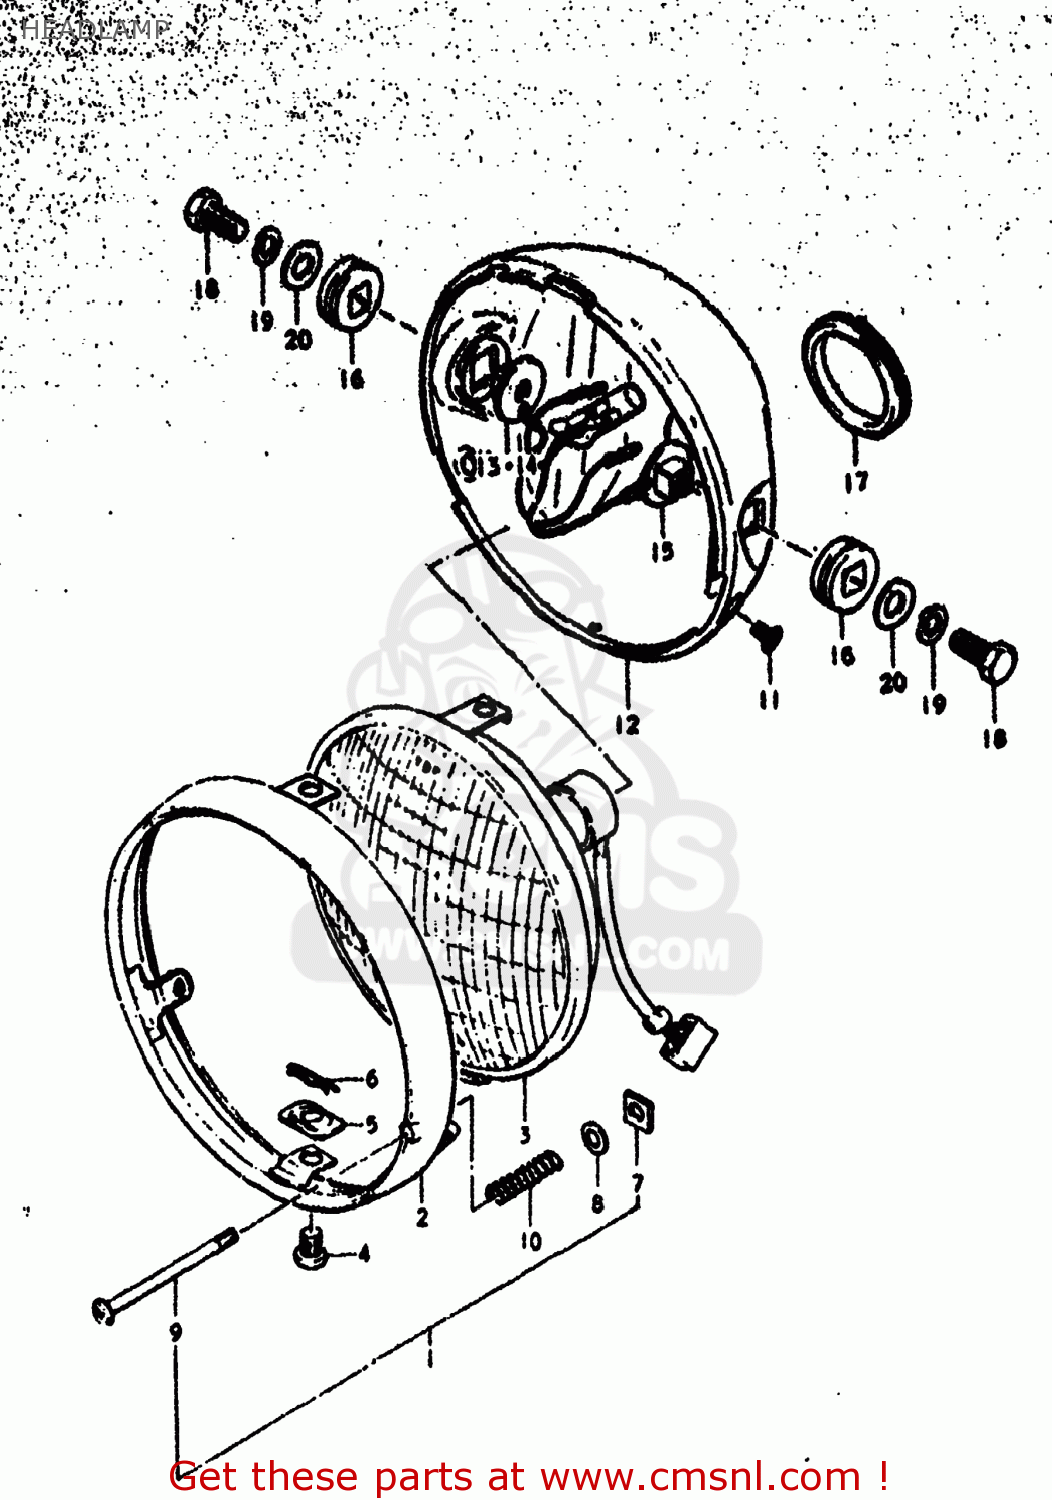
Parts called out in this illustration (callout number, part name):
1	HEADLAMP ASSEMBLY
2	RIM,HEADLAMP
3	LAMP UNIT
4	SCREW
5	NUT,ADJUSTING
6	CUSHION,HEADLAMP
7	NUT,HEADLAMP ADJUSTER
8	WASHER
9	SCREW,HEADLAMP ADJUST
10	SPRING,HEADLAMP ADJUST
11	SCREW(5X12)
12	HOUSING COMP,HEADLAMP
13	SPACER, HOUSING RH
14	SPACER, HOUSING RH
15	SPACER, HOUSING LH
16	CUSHION,HEADLAMP HOUSING
17	GROMMET,HEADLAMP HOUSING
18	BOLT
19	LOCK WASHER
20	WASHER
